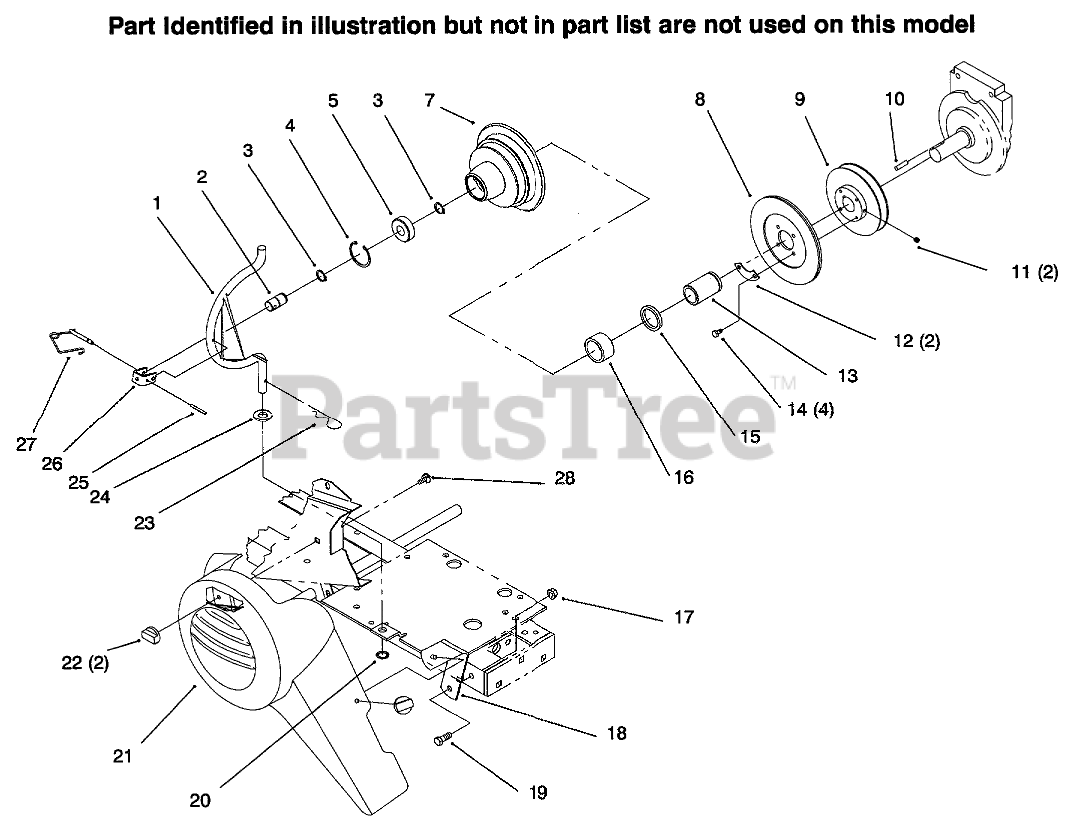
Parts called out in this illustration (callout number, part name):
1	ROD-HOUSING
2	SHAFT-PTO
3	Ring-Snap
4	RING-RETAINING
5	BEARING-BALL
7	Housing-Clutch
8	Facing-Clutch
8	ASS'Y-CLUTCH PLATE
9	PULLEY
11	SCREW-SET, HSH
12	RETAINER
13	RACE-BEARING
14	SCREW-HEX HD CAP
15	SEAL-OIL
16	Seal
17	NUT-FLANGE
18	Bracket
19	SCREW-HH
20	RING-REINFORCED CIRC
21	GUARD - BELT
22	NUT - WING
23	PIN-COTTER, HAIR
24	WASHER-FLAT
26	CLEVIS
27	LOCKING PIN ASM
28	Retainer-Bolt
30	SCREW-HWHTF
31	WASHER-PLAIN
